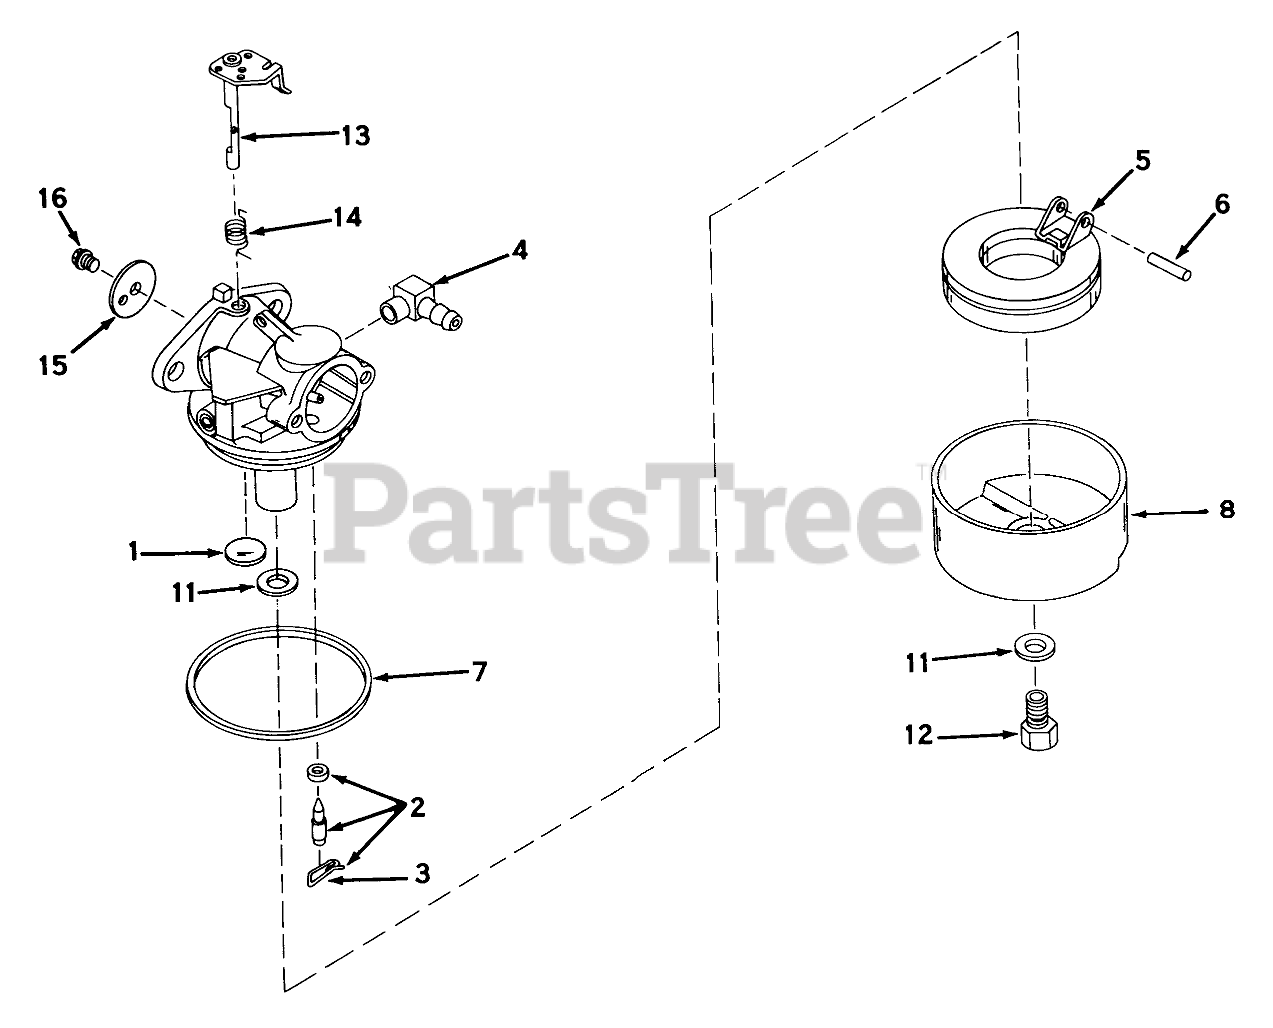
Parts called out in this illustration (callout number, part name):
1	Plug-Welch, Atmospheric Vent
2	Inlet Needle, Seat &Clip Assy. (Incl. No. 3)
3	Clip-Spring
4	Fitting Fuel Inlet
5	Float,Carburetor
6	Shaft-Float
7	O Ring-Bowl, Float
8	Bowl Float
11	Gasket-Bowl
12	Nut, Float Bowl
13	Throttle Shaft and Lever ASM
14	Spring, Return
15	Throttle-Shutter
16	Screw-Shutter
